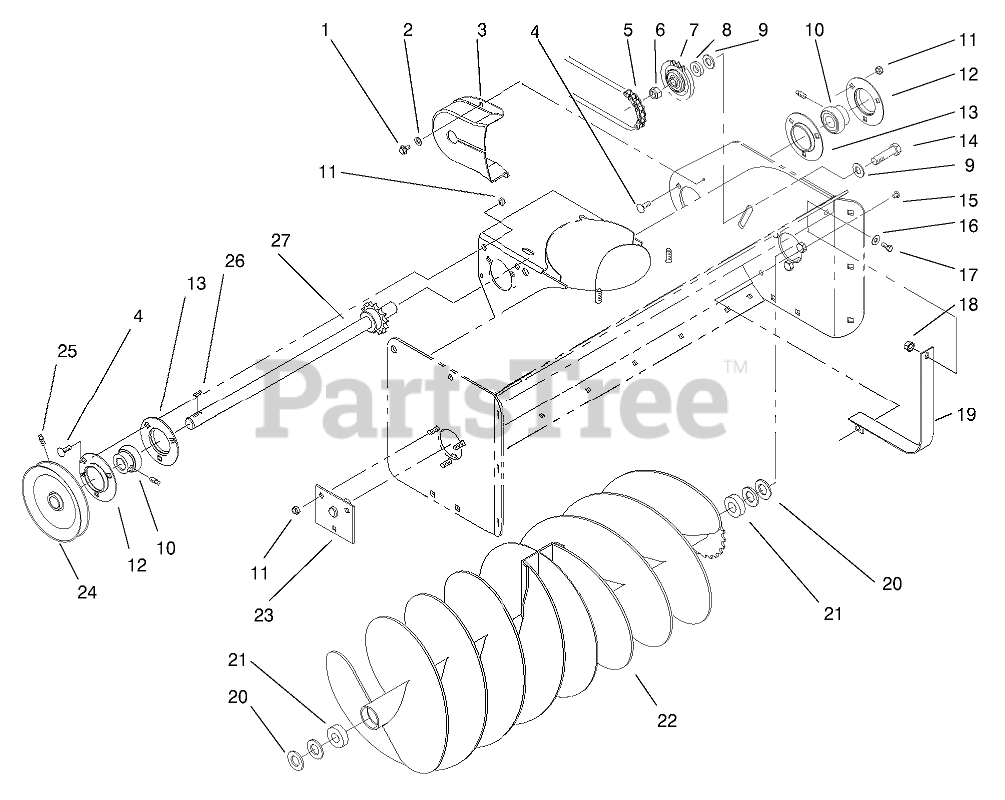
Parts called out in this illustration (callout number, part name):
1	SCREW-HWH
2	WASHER-FLAT
3	GUARD-CHAIN
4	BOLT-CARR
5	CHAIN-64 PITCHES
6	NUT-LOCK, NI
7	Idler Sprocket
8	SPACER
9	WASHER-FLAT
10	BEARING AND COLLAR
11	NUT-LOCK, NI
12	FLANGE-ZERK RELUBE
13	Flange
14	SCREW-HH
15	SCREW-HHF
16	WASHER-FLAT
17	SCREW-HH
18	NUT-KEPS
19	GUARD-INNER
20	WASHER-FLAT
21	BEARING-BALL
22	Auger
23	SUPPORT
24	PULLEY
25	SCREW-SQH
26	Key
27	SHAFT W/SPRKT
